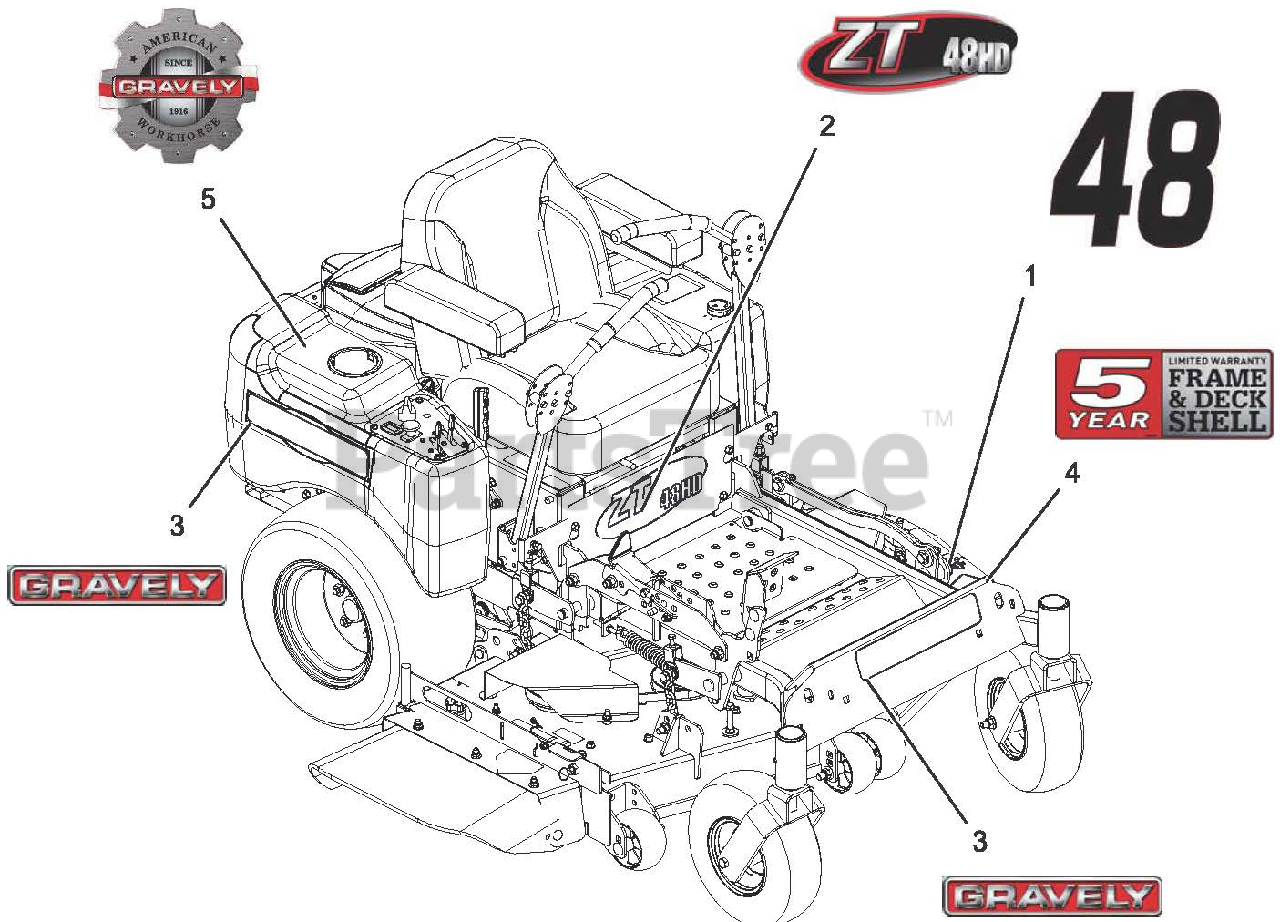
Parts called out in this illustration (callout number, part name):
1	DECAL, 48"
2	DECAL, 48HD
3	DECAL, FUEL TANK - GRAVELY
4	DECAL, DECK WARRANTY - FAB GRAVELY
5	DECAL, GRAVELY HERITAGE - SMALL
